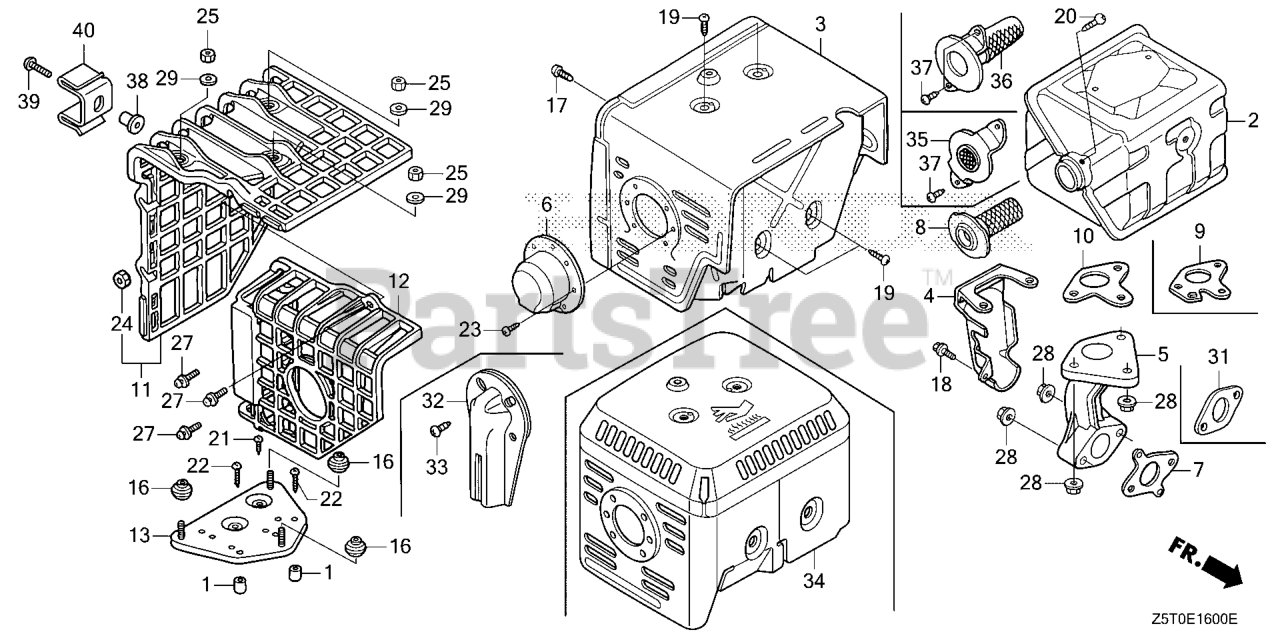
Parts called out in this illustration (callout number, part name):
2	MUFFLER
4	PROTECTOR, EX. PIPE
6	CAP, MUFFLER
7	GASKET, EX. PIPE
9	GASKET, MUFFLER (ARRESTER)
9	GASKET, MUFFLER (ARRESTER)(THAI LEAKLESS)
17	SCREW, TAPPING (6X10)
18	BOLT, FLANGE (6X12) (CT200)
19	SCREW, TAPPING (5X8)
23	SCREW, TAPPING (4X6) (TO INSTALL OPTIONAL SPARK ARRESTER)
28	NUT, FLANGE (8MM)
34	PROTECTOR, MUFFLER
36	ARRESTER, SPARK
37	SCREW, TAPPING (5X8)
